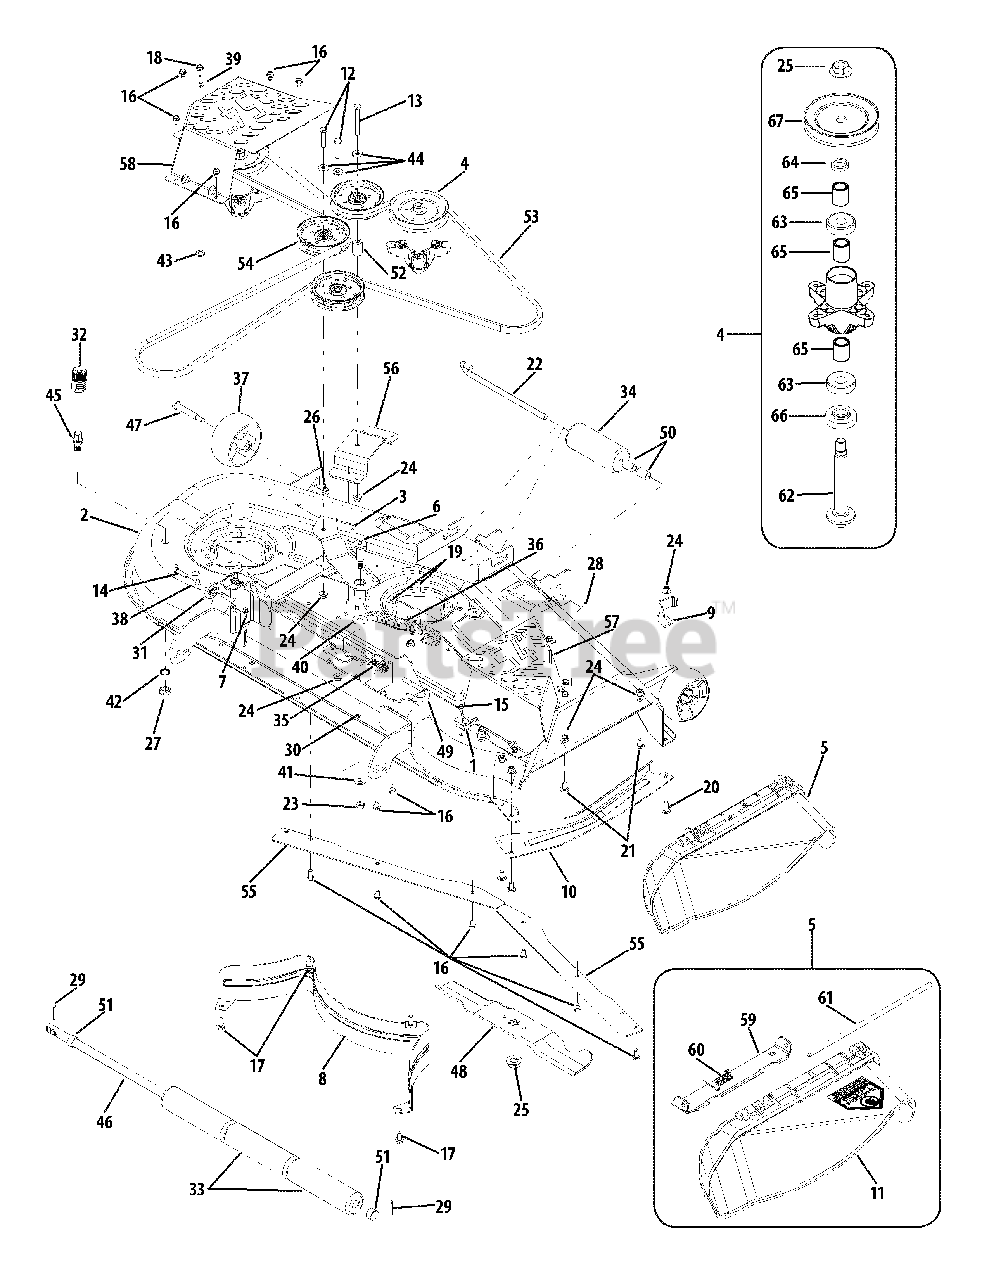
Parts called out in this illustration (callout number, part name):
1	Retainer Bracket
4	Spindle Assembly
5	Discharge Chute Assembly
6	Shoulder Bolt Assembly
11	Chute Deflector
12	Hex Cap Screw, 3/8 -16 x 1.75
13	Hex Cap Screw, 3/8-16 x 3.0
14	Hex Cap Screw, 5/16-18 x 1.25
15	Hex Washer Head Screw, 1/4-20 x .5
16	Hex Washer Head Screw, 5/16-18 x .5
17	Hex Washer Head Screw, 3/8 -16 x .75
18	Hex Washer Head Screw, 5/16-18 x .875
19	Hex Washer Head Screw, 5/16-18 x .75
20	Carriage Screw, 3/8 -16 x 1.0
21	Carriage Screw, 3/8-16 x .75
22	Roller Pin, .5 x 10.06
23	Hex Lock Nut,7/16-14
24	Hex Insert Flange Lock Nut,3/8 -16
25	Hex Flange Nut,5/8 -18
26	Hex Flange Lock Nut, 3/8-16
27	Hex Nut, M16-1.5
28	Cotter Pin, 3/32 x 1.0
29	Cotter Pin, 5/32 x 1.25
30	Cotter Pin, 1/8 x 1.25
31	Deck Adjustment Gear
32	Water Nozzle Adapter
33	Deck Roller, 7.895
34	Front Roller
35	Compression Spring
36	Extension Spring, 1.0 x 6.140
37	Deck Ball Wheel, 5.0
38	Lock Washer, 5/16
39	Flat Washer, .344 x .688 x .065
40	Flat Washer, .442 x 1.39 x .06
41	Bell Washer, .45 x 1.0 x .062
42	Lock Washer
43	Flat Washer, .407 x .812 x .135
44	Flat Washer, .38 x .93 x .110
45	Deck Wash Nozzle
46	Shaft, .75 x 26.893
47	Shoulder Screw, .5 x 2.5 x 3/8 -16
48	Blade, 18.5
49	Deck Hanger Rod
50	Spacer, .55 x .75 x 1.125
51	Spacer, .82 x 1.0 x.53
52	Spacer, .38 x .9 x 1.313
53	V-Belt Type B Sec x 143
54	Idler Pulley, 4.25 Dia
59	Chute Mounting Bracket
60	Torsion Spring
62	Spindle Shaft, 6.95
63	Ball Bearing
64	Spacer, .79 x 1.25 x .175
65	Spacer, .80 x 1.10 x 1.32
66	Spacer, .79 x 1.82 x .55
67	V-Type Pulley, 5.39
